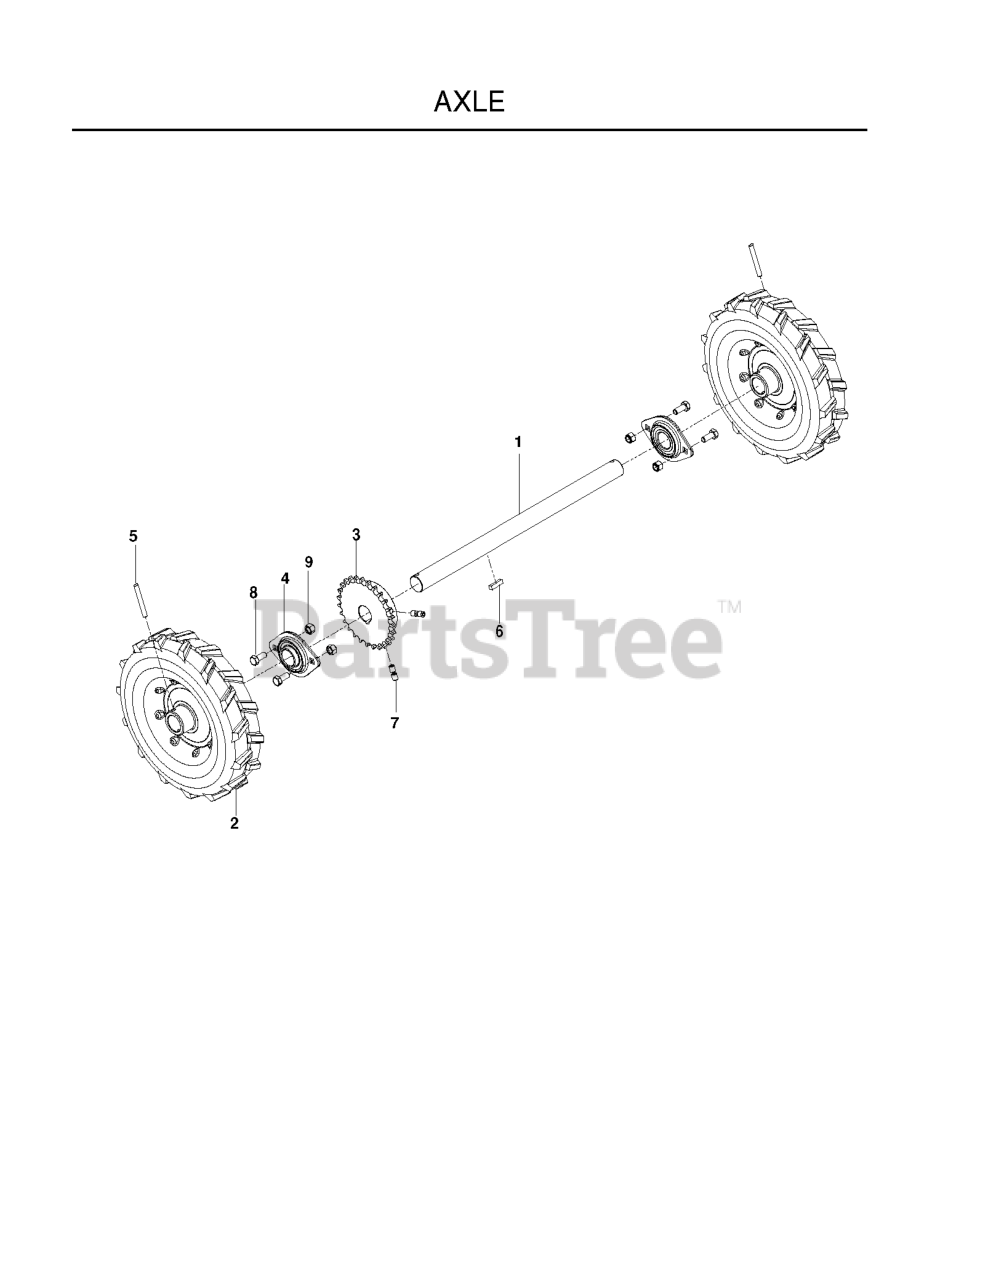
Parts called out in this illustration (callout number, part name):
1	AXLE SC18A
2	WHEEL
3	SPROCKET W/KEY, ROTOR 27 TEETH
4	FLANGE BEARING ZINC PLATED 1"
5	SPIRAL PIN 1/4 X 1-1/2
6	KEY 1/4 SQ X 1.0
7	SET SCREW 5/16 NYLOC
8	HCS 5/16C X 3/4
9	NUT 5/16 NYLOC
